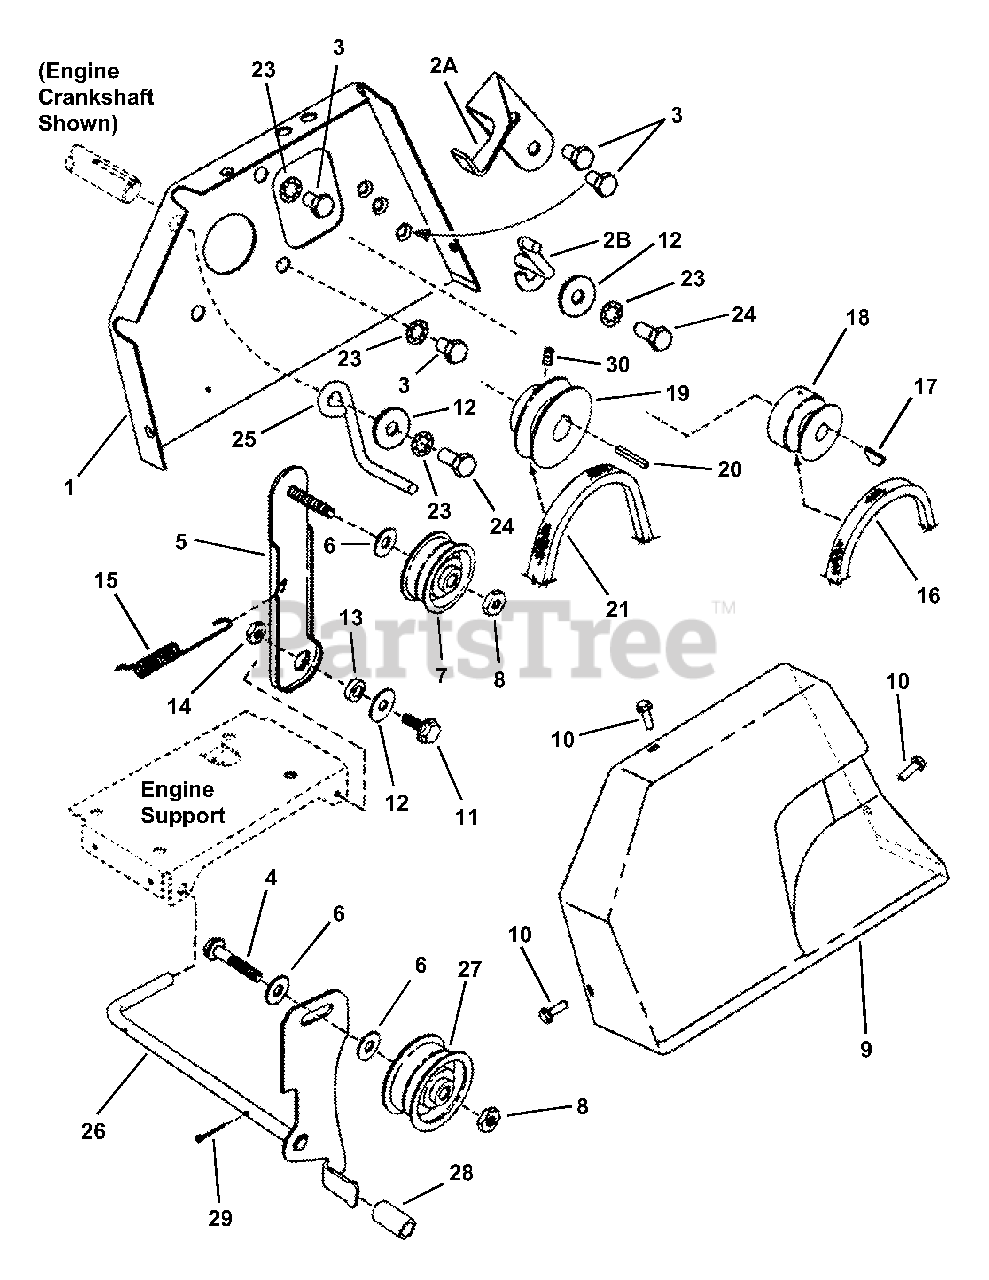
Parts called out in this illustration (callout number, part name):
1	PLATE, Engine
2A	GUIDE, Belt (I55224 & EI55224 also I7244 & EI7244 late production)
2B	GUIDE, Belt (I7244 & EI7244 early production)
3	SCREW, 5/16-18 x 1/2" Hex Head Cap, Grade 5
4	SCREW, 3/8-16 x 1-3/4" Hex Head Cap, Grade 5
5	BRACKET, Idler
6	WASHER, 3/8" Flat
7	IDLER, 2" O.D.
8	NUT, 3/8-16 Hex Center Lock, Grade B or 5
9	COVER, Belt
10	SCREW, #10-24 x 5/8" Self-Tapping, Gr. 5
11	SCREW, 5/16-18 x 1" Hex Head Cap, Grade 5
12	WASHER, 5/16" Flat
14	NUT, 5/16-18 Hex Center Lock, Grade B or 5
15	SPRING
16	BELT, Traction
17	KEY, 1/8 x 5/8" Woodruff
18	PULLEY, P.T.O. (I55224 & EI55224)
19	PULLEY, Auger Drive
20	KEY, 3/16x3/16x1"
21	BELT, Blower
23	WASHER, 5/16" Internal Tooth Lock
24	SCREW, 5/16-24 x 3/4" Hex Head Cap, Grade 5
25	GUIDE, Belt
26	BRAKE ARM & ROD
27	IDLER, 2-1/2" Flat
28	TUBE, Brake
29	PIN, 1/16 x 3/4" Cotter
30	SCREW, 1/4-20 x 5/16 Socket Set
